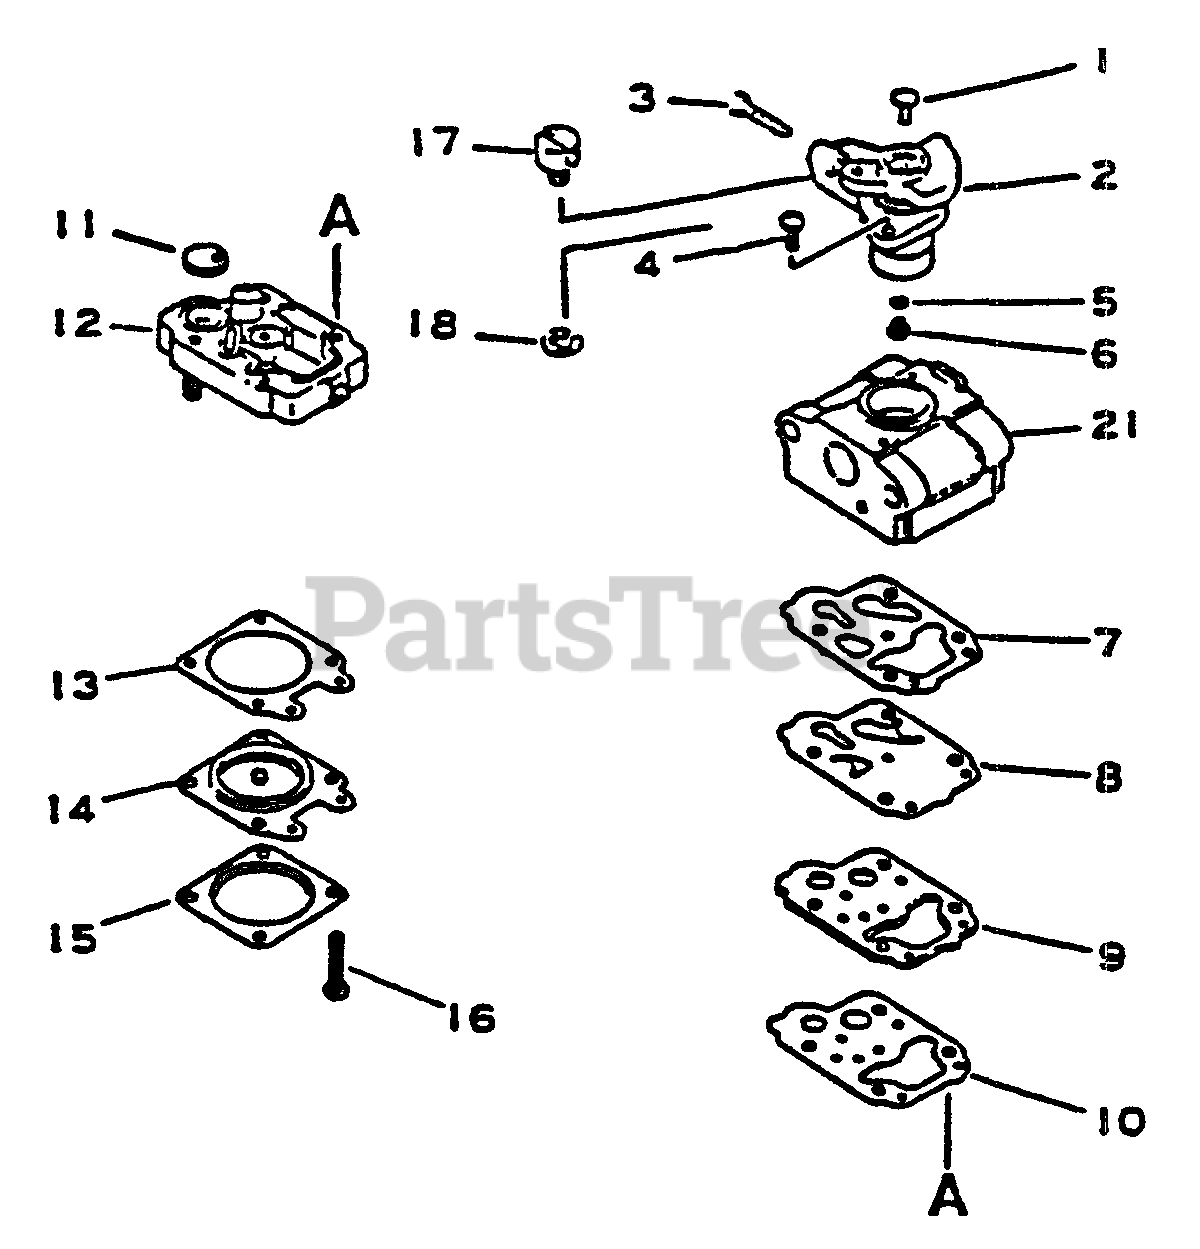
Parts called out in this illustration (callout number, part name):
2	THROTTLE VALVE ASSY
4	SCREW, THROTTLE COLLAR
5	O-RING
6	JET
7	GASKET, PUMP
8	DIAPHRAGM, PUMP
9	COVER, PUMP
10	GASKET, PLATE
11	STRAINER
12	BASE, PURGE
13	GASKET, METERING
14	DIAPHRAGM, METERING
15	COVER, METERING DIAPHRAGM
